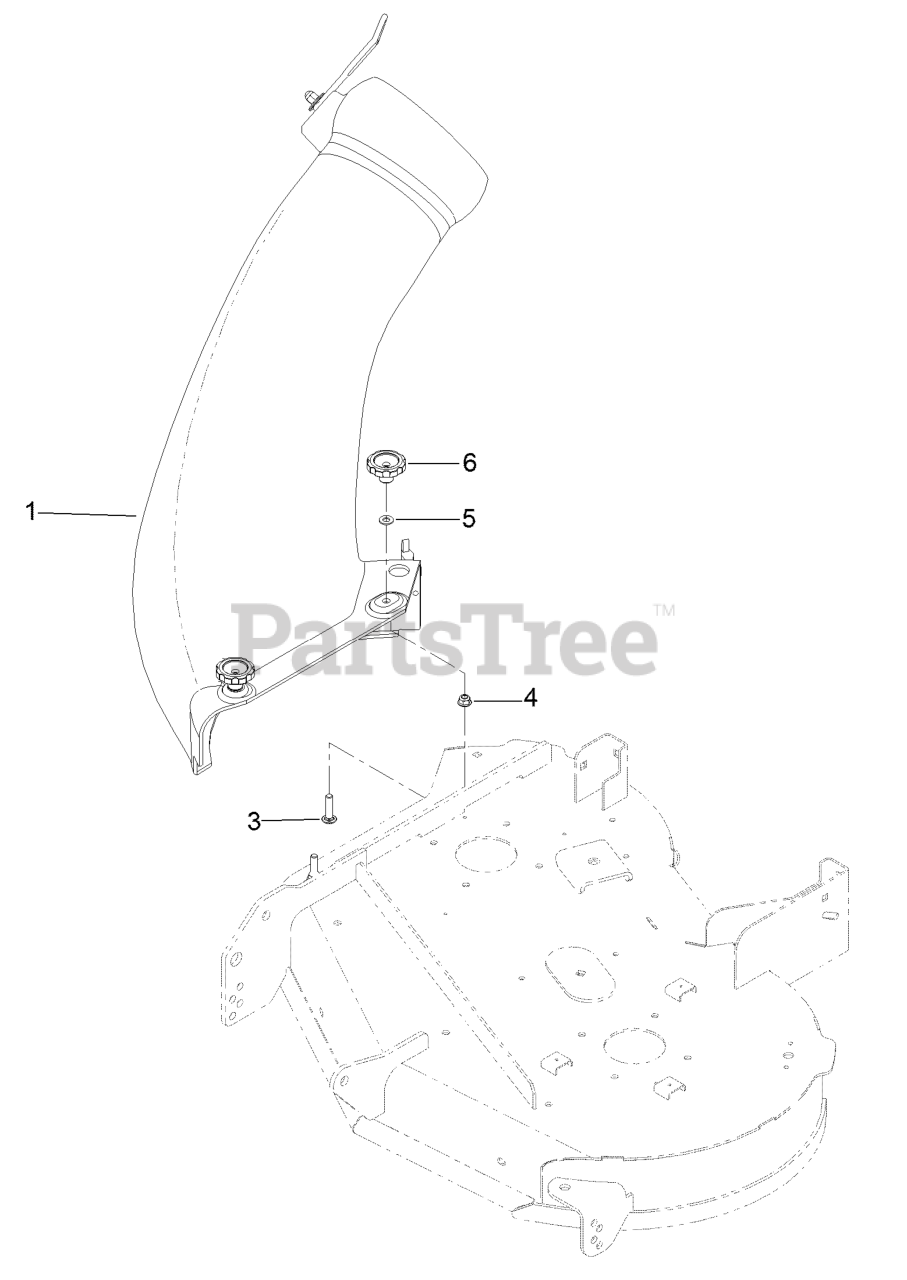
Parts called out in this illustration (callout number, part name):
1	34 INCH CHUTE ASM
3	SCREW-CARR
4	NUT-HF, NI
5	WASHER-PLAIN
